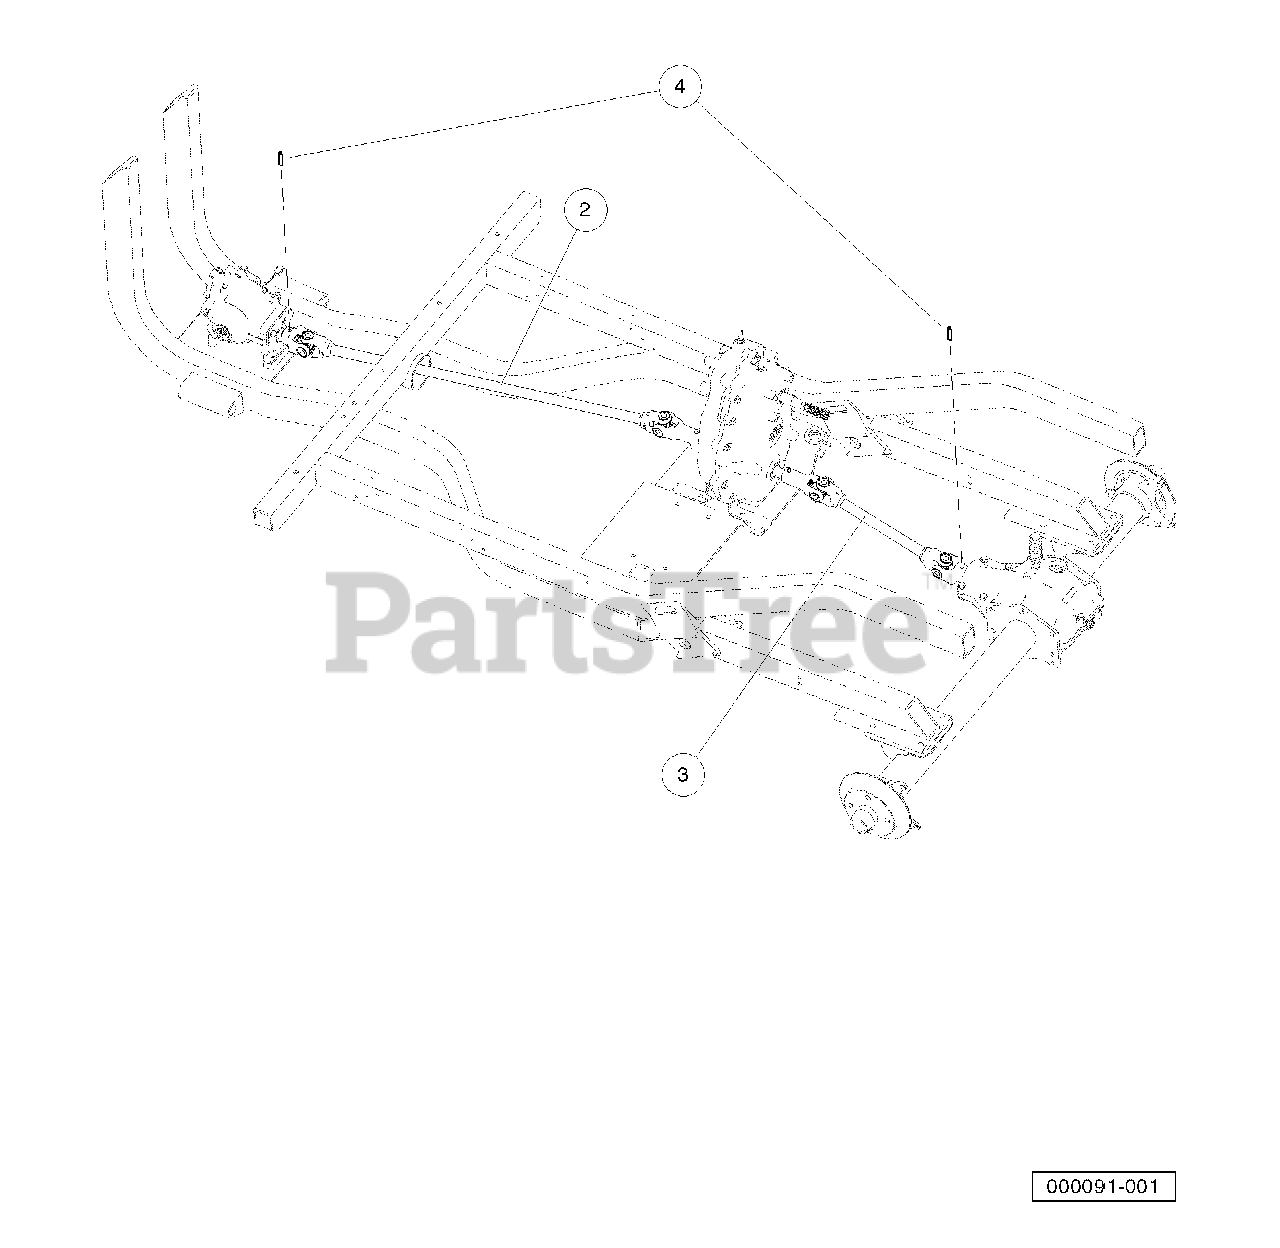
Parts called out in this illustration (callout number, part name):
1	Inst, Prop Shafts, Awd
2	Prop oh 3ft, Front
3	Prop Shaft, Rear
4	Pin, Spring, 5/16 X 1-1/2 Hd
